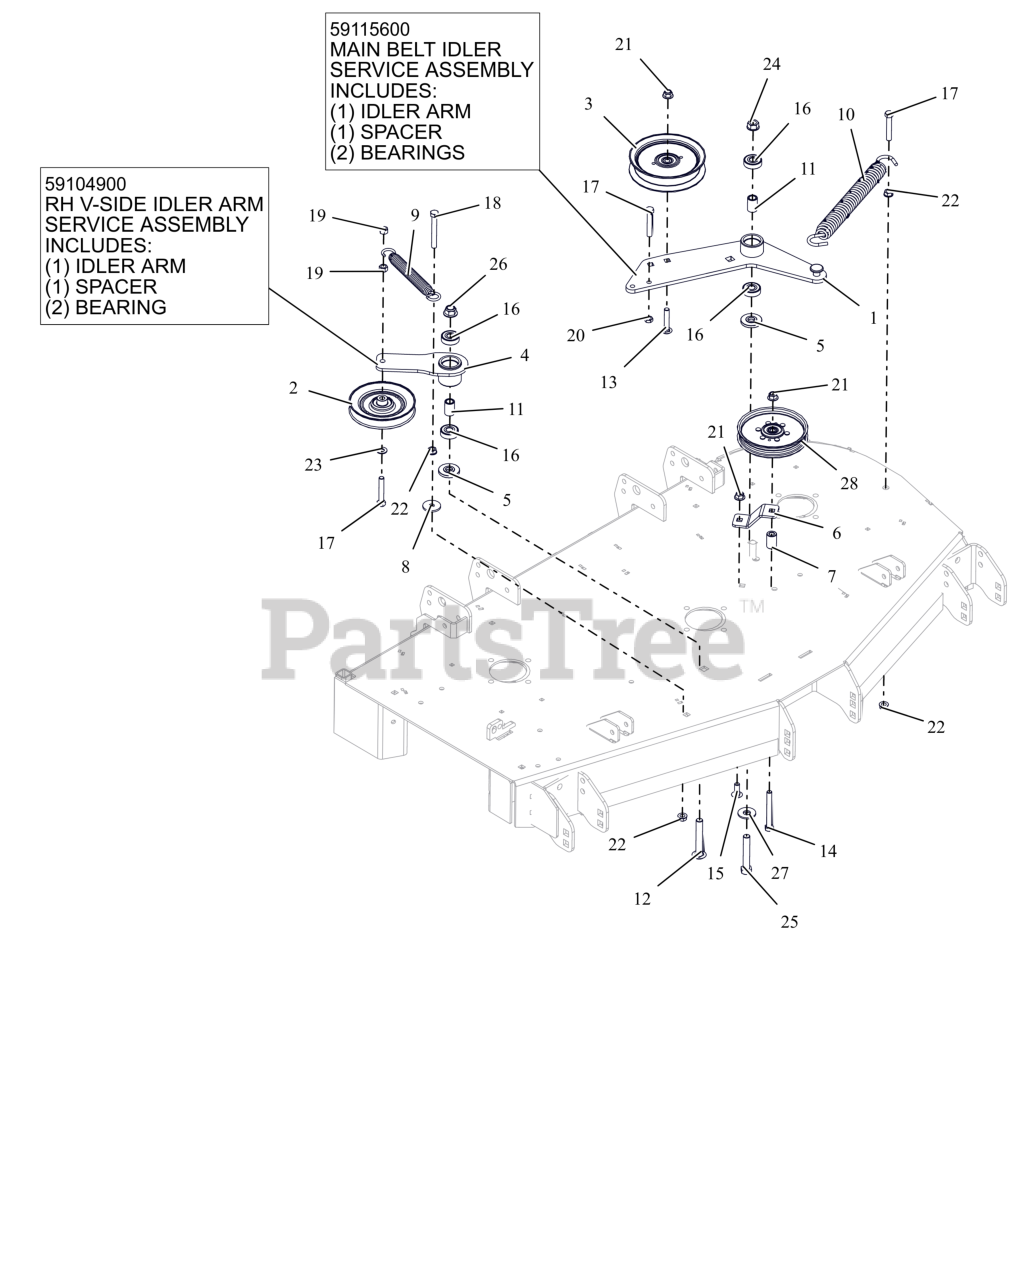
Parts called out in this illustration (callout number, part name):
1	WLDMT, DECK PTO IDLR ARM
1	ASSEMBLY, MAIN BELT IDLER
2	IDLER, V-5.00"
3	IDLER, FLAT 5.00"
4	WLDMT, DECK RH IDLER ARM
4	RH V-SIDE IDLER ARM ASSEMBLY
5	SPACER, IDLER ARM
6	PTO FIXED IDLER MTG BRKT -RED
7	BUSHING, SLV .380X.750X1.190
8	WSHR,FLT .406X1.375X.135 ZCC
9	SPRING, EXTENSION
10	SPRING, EXTENSION
11	SPACER .510 X .75 X 1.1485
12	BTL,RHSSN .500-13 X 3.25 G5 ZCC
13	BLT,RHSSN.375-16X2.00 G5 ZCC
14	BLT, HEX .38-16X3.25 G5 ZCC
15	BLT,RHSSN .38-16X1.00 G5 ZCC
16	BRG-BALL .500X1.38X.437
17	BLT,HEX .38-16X2.25 G5 ZCC
18	BLT, HEX .38-16X3.00 G5 ZCC
19	NUT-LK-CTR .38-16 ZC120
20	NUT-JAM .375-16 G2 ZCC
21	NUT,NYL-FLG .38-16 GF ZCC
22	NUT, SPNLK-FLG .38-16 G5 ZCC
23	WSHR,FLT .406X.812X.065 ZCC
24	NUT-LK-CTR-FLG .500-13 GG ZCC
25	BLT, HEX .50-13X3.00 G5 ZCC
26	NUT,NYL-FLG .50-13 GF ZCC
27	WSHR,FLT .563X1.375X.109 ZCC
28	PULLEY, FLAT IDLER
